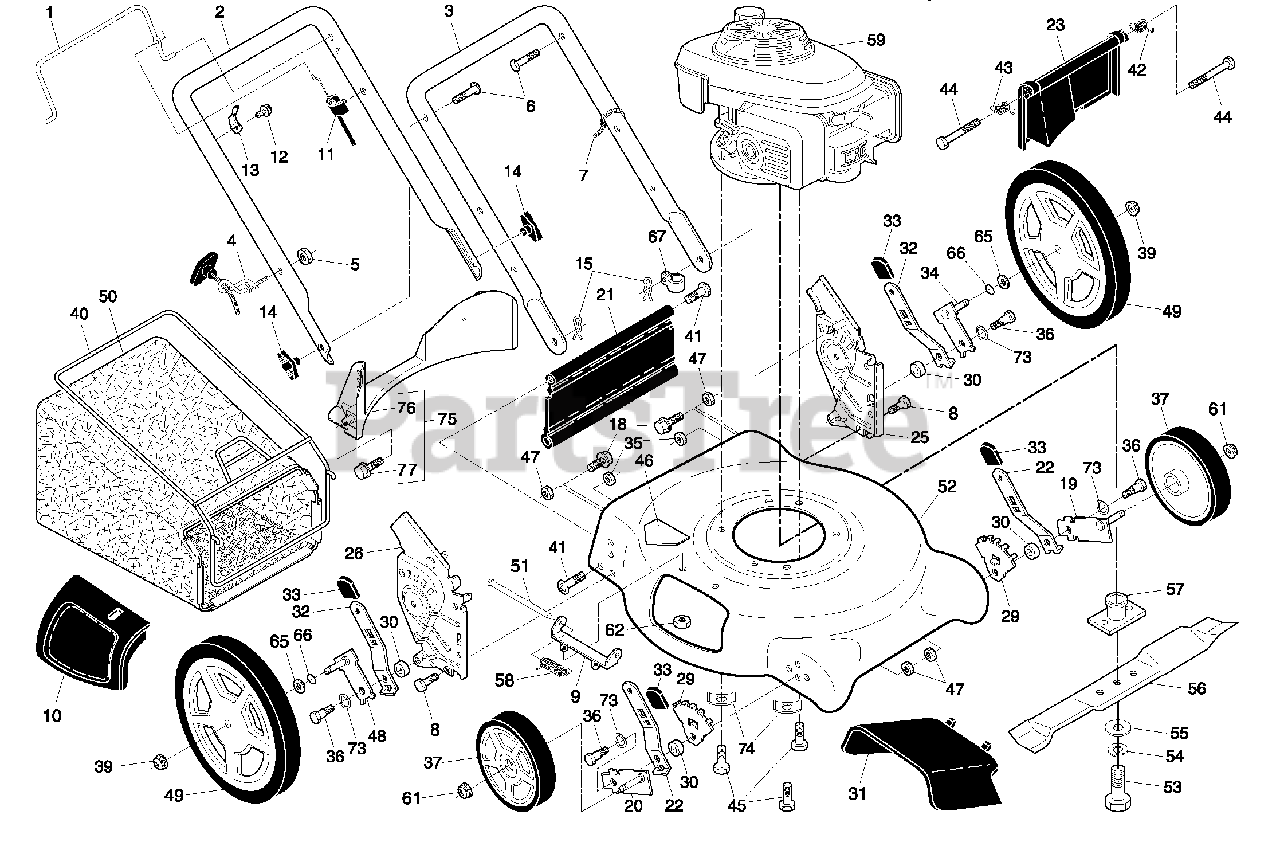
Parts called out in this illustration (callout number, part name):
1	Control Bar
2	Upper Handle
3	Lower Handle
4	Rope Guide
6	Handle Bolt
7	Wire Tie
8	Bolt, Hex Head 5/16-18 x 3/4
9	Hinge Bracket
10	Mulcher Door
11	Engine Zone Control Cable
12	Hex Washer Head Screw #10-24 x 1/2
13	Up-Stop Bracket
14	Handle Knob
15	Hairpin Cotter
18	Screw
19	Axle Arm Assembly, Front, LH
20	Axle Arm Assembly, Front, RH
21	Kit, Rear Skirt
22	Selector Spring, Front
23	Rear Door Assembly
25	Handle Bracket, LH
26	Handle Bracket, RH
29	Wheel Adjusting Bracket
30	Spacer
31	Discharge Deflector
32	Selector Spring, Rear
33	Selector Knob
34	Axle Arm Assembly, Rear, LH
35	Locknut, Hex 5/16-18
36	Shoulder Bolt 5/16-18
37	Wheel & Tire Assembly, Front, 8"
39	Nut, Hex
40	Frame, Grassbag
41	Screw, Hinge
42	Spring, LH
43	Spring, RH
44	Bolt, Rear Door
45	Hex Head Thread Rolling Screw 3/8-16 x 1
46	Danger Decal
47	Nut, Hex
48	Axle Arm Assembly, Rear, RH
49	Wheel & Tire Assembly, Rear 12 x 1-3/4
51	Hinge Rod
52	Kit, Housing
53	Screw, Hex Head, Grade 8 3/8-24 x 1-3/8
54	Helical Lockwasher
55	Hardened Washer
56	21" Blade
57	Blade Adapter
58	Hinge Spring
61	Flanged Locknut
62	Nut, Hex
65	Washer, Flat
66	O-Ring
67	Clip, Cable
73	Washer, Curved, Cylindrical
74	Washer, Special, Engine
75	Kit, Rear Baffle
76	Baffle, Rear
77	Screw, Rear Baffle
77	Operator's Manual, English
77	Operator's Manual, French
77	Repair Parts Manual
